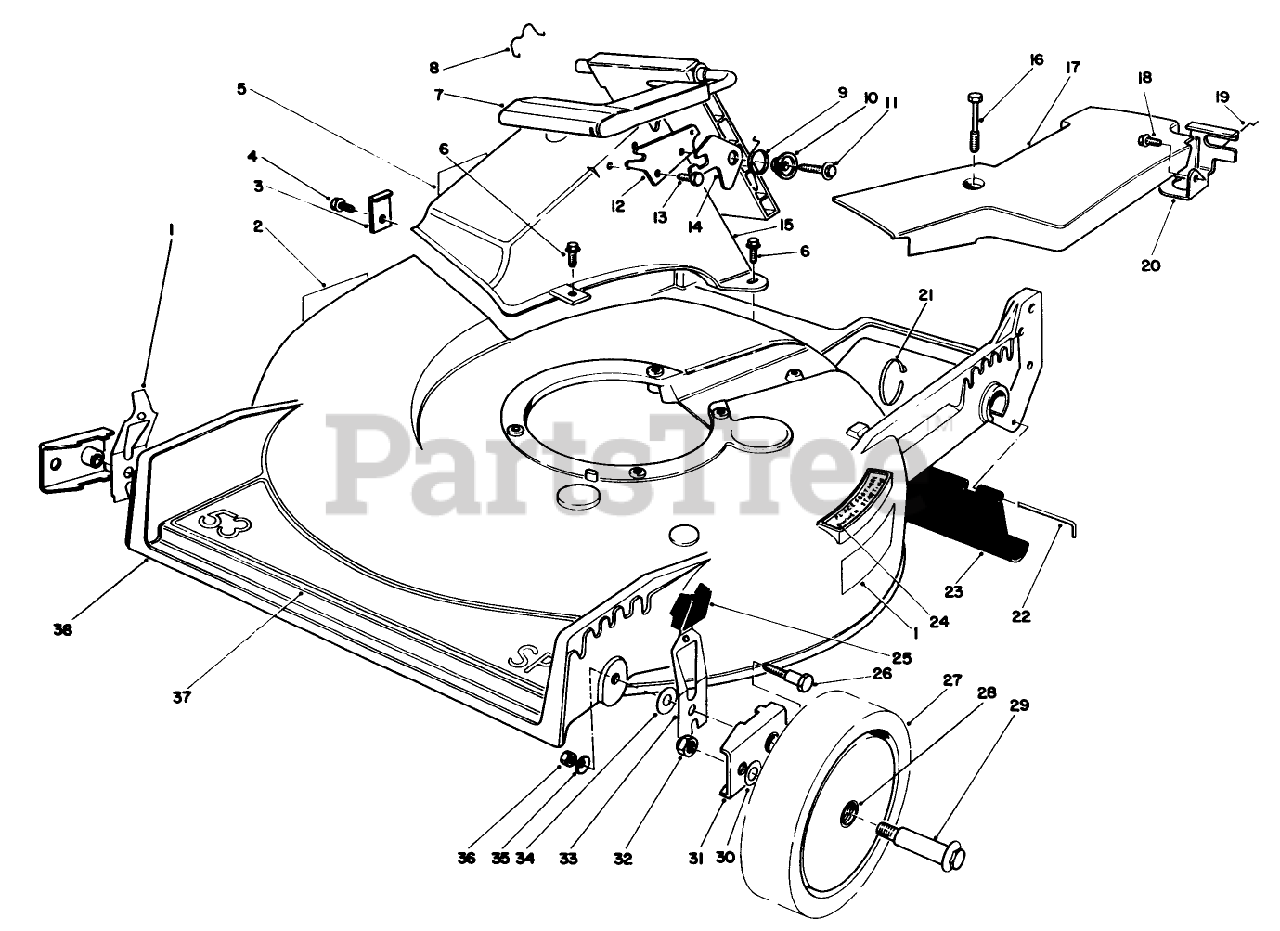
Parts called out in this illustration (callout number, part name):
3	TUNNEL CLIP
4	SCREW
6	SCREW-HWH
8	DOOR RET SPRING
9	TORSION SPRING
10	Latch Spacer
11	SCREW-HWH
12	DOOR LATCH PLATE
13	SCREW-PLASTITE
14	SAFETY LATCH
16	SCREW-HWH
18	SCREW-THD ROLL, HWH
19	RETAINER-CABLE
21	TIE-CABLE
22	ROD-SHIELD
24	DECAL - STEP PAD INT'L
25	KNOB-ARM
26	PIVOT SCREW
28	BUSHING
29	BOLT-WHEEL
30	WASHER
31	HP PIVOT ARM ASM
34	WASHER-PIVOT
35	WASHER-BELLEVILLE
36	NUT-LOCK, NI
